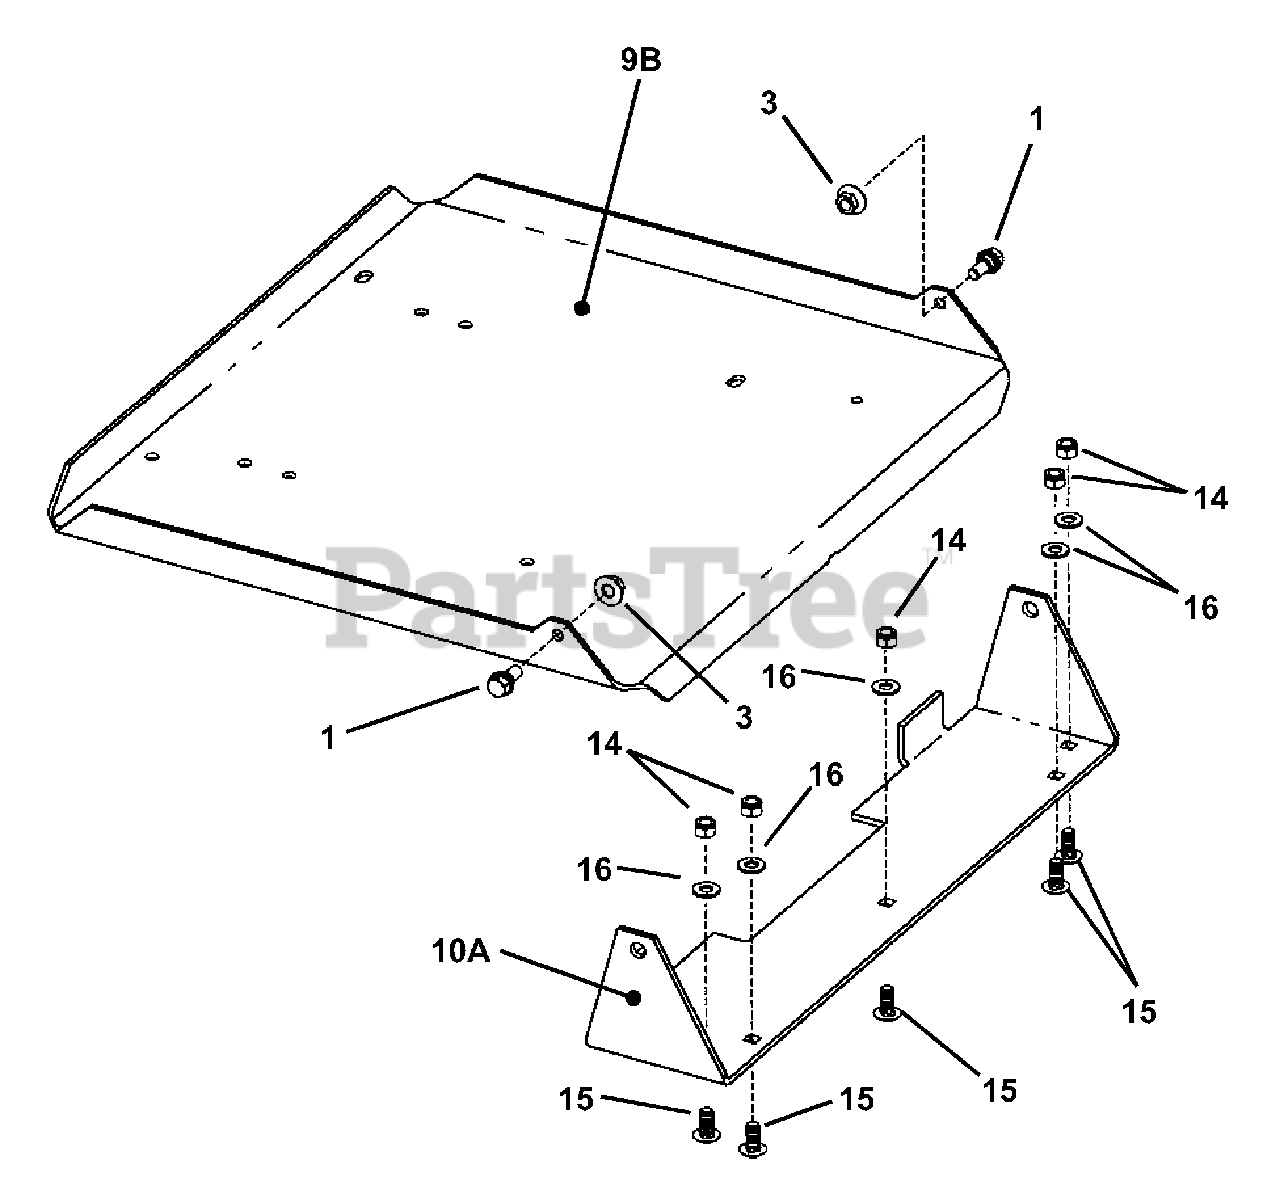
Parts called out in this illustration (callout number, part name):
1	BOLT, 5/16-18 x 3/4" Shoulder
3	NUT, 5/16-18 Hex Flange Lock
9B	PLATE, Seat Support (Model ZMT2500KH Only)
10A	BRACKET, Seat Hinge (Model ZMT2500KH Only)
14	NUT, 5/16-18 HEX NYLON LOCK
15	BOLT, 5/16-18 x 3/4 Carriage Grade 5
16	RETAINER, 5/16" Bolt
